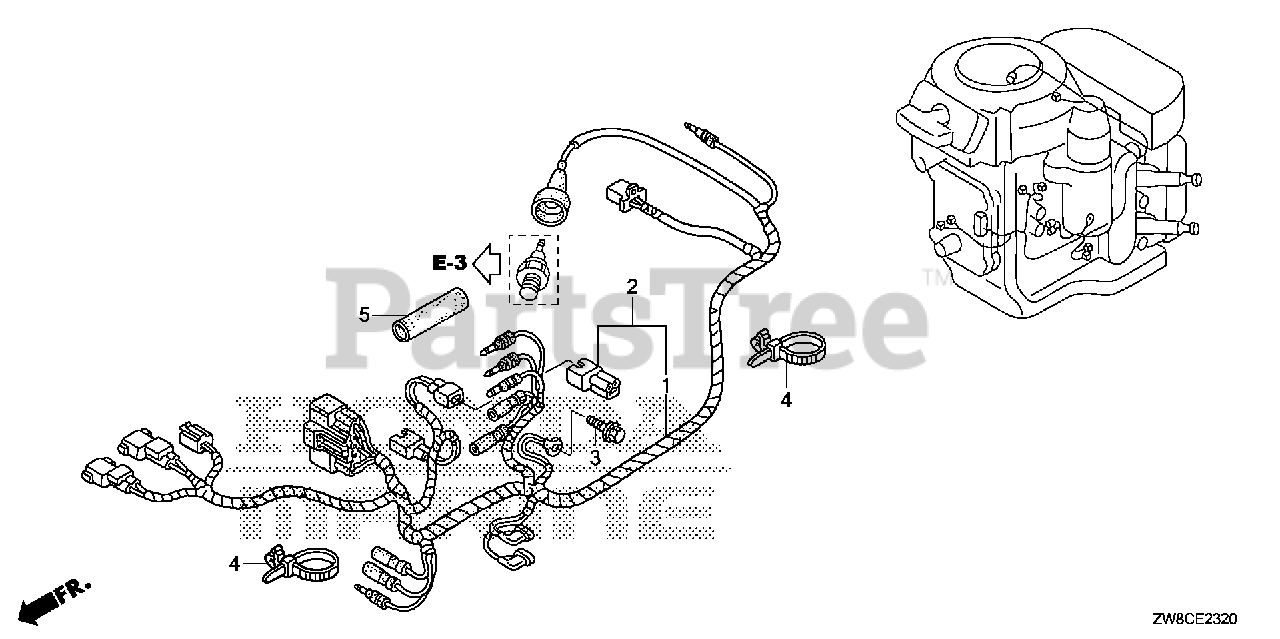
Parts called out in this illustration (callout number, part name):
1	WIRE HARNESS ASSY.
3	BOLT, FLANGE (6X12)
4	BAND, WIRE (95MM)
5	TUBE, RUBBER (11.5X14.5)
